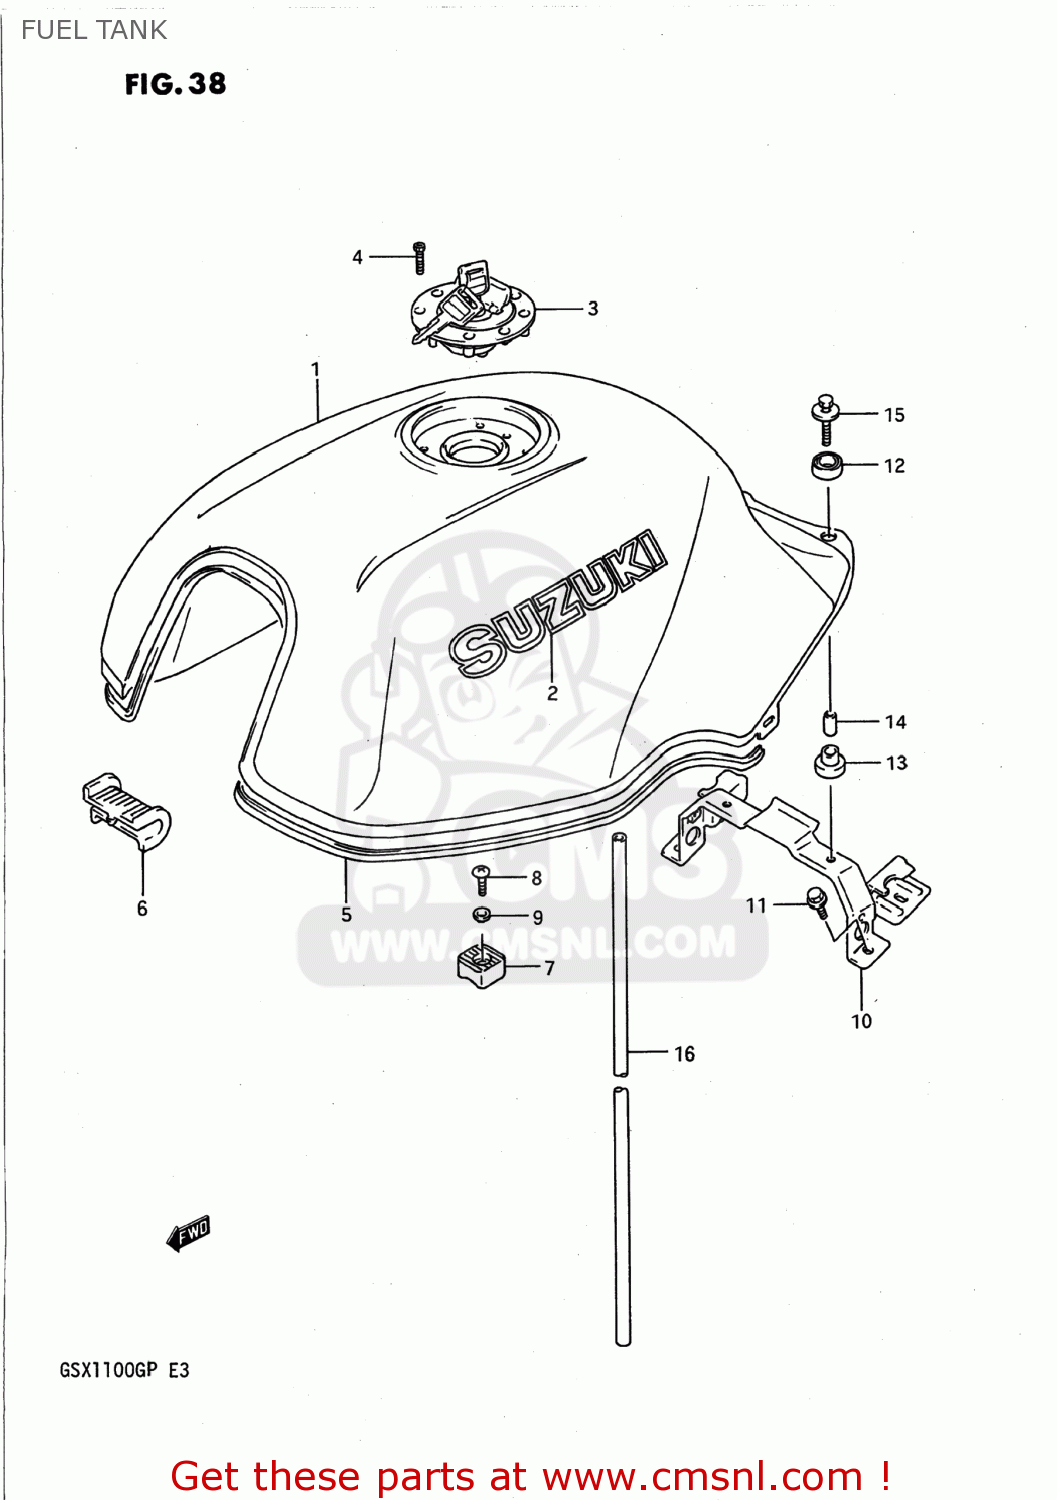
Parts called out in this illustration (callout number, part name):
1	TANK ASSEMBLY,FUEL
2	EMBLEM
3	CAP SET,FUEL TANK
4	BOLT(5X20)
5	MOLDING,FUEL TANK
6	CUSHION,FUEL TANK,FRONT
7	CUSHION,FUEL TANK SIDE
8	SCREW
9	WASHER
10	BRACKET COMP,FUEL TANK
11	BOLT
12	CUSHION
13	CUSHION
14	SPACER
15	BOLT(6X35)
16	HOSE(7X10.2X600)
